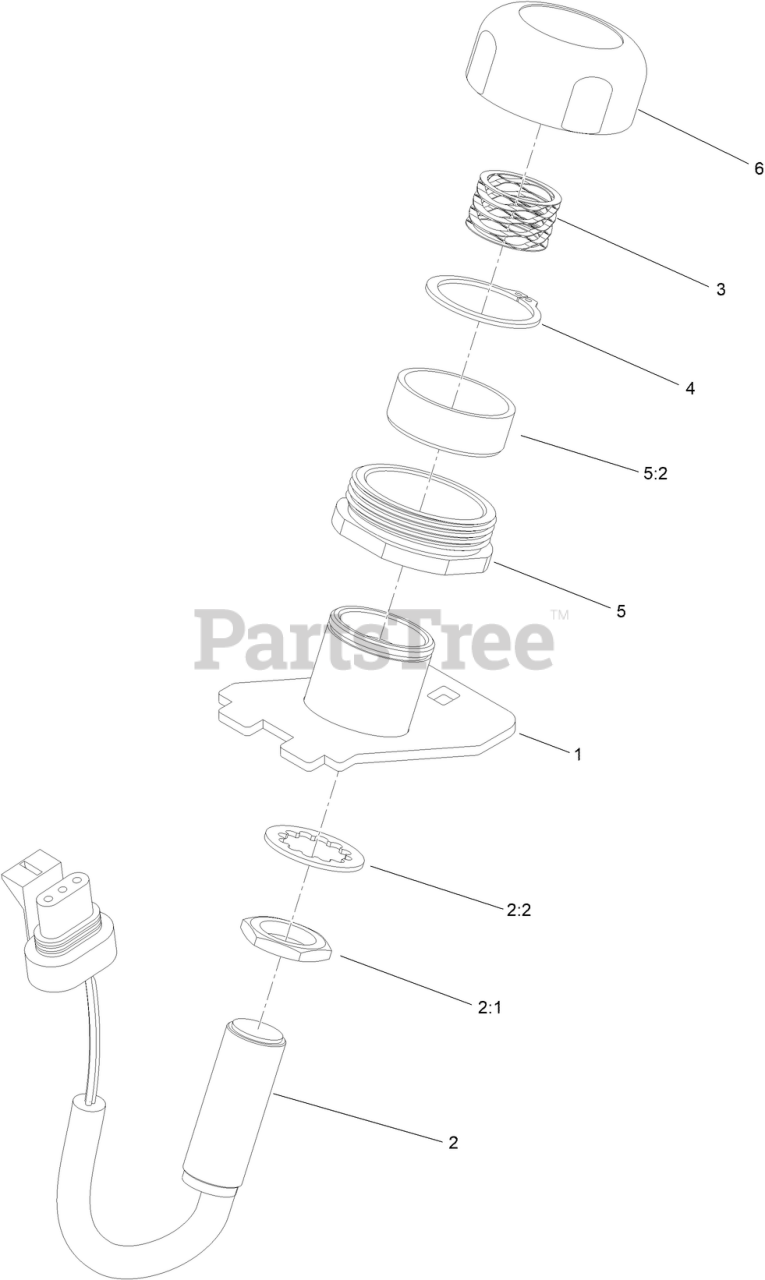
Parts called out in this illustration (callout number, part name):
1	MOUNT-SWITCH, FOOT
2	PROXIMITY SWITCH ASM
2:1	NUT-HEX
2:2	WASHER-LOCK, INTERNAL TOO
3	SPRING-WAVE
4	RING-RETAINING, EXT
5	GUIDE-BUTTON
5:2	BUSHING-SLEEVE
6	BUTTON-FOOT
